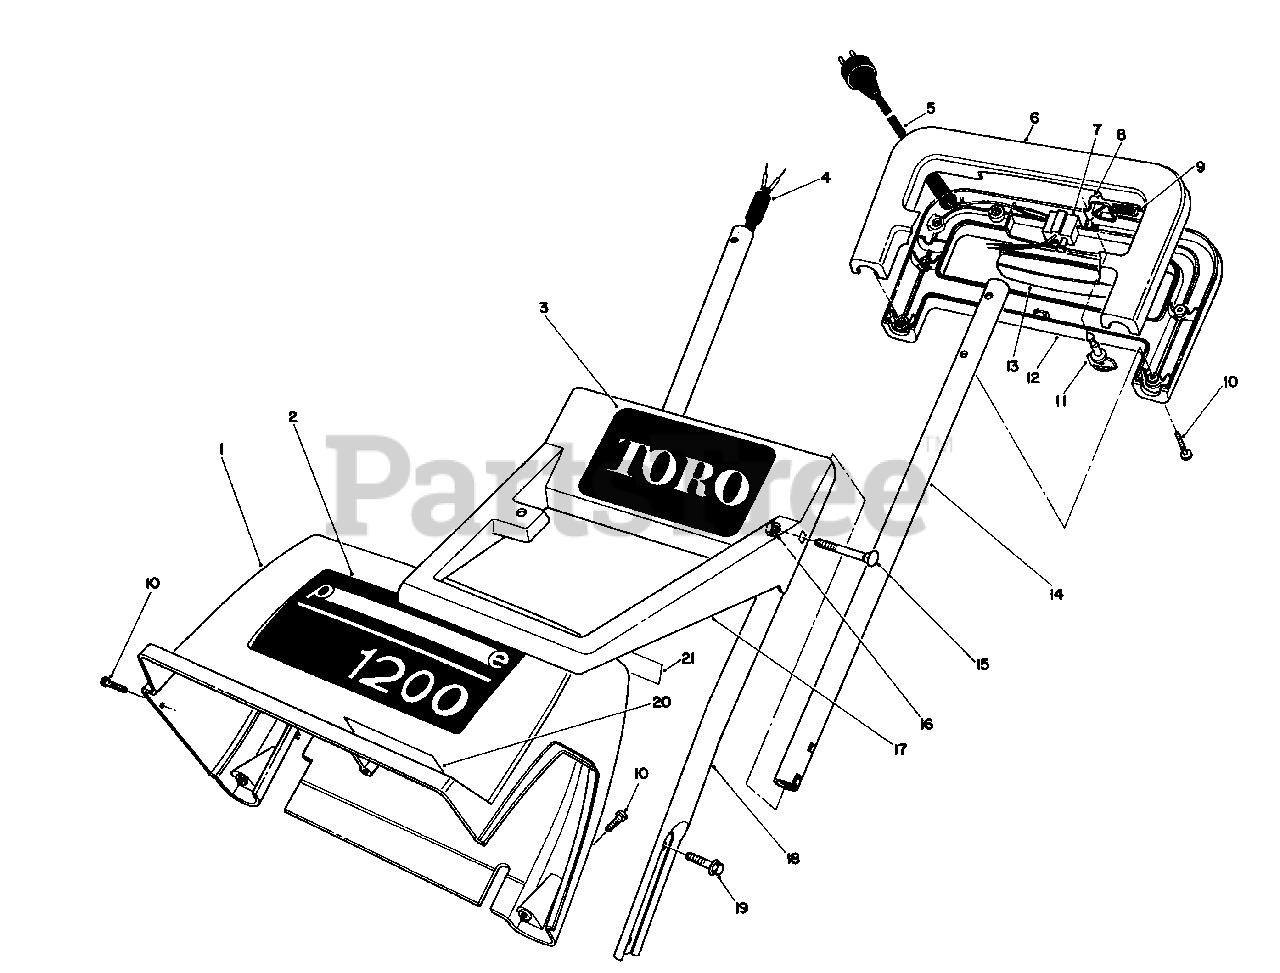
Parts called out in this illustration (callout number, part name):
1	Shroud (Incl. Ref. #2, 20, & 21)
2	Decal-1200
3	Decal-Toro
4	Wire Harness
5	Cord Supply
6	Handle-Upper Control
7	Switch-Starter
8	Switch-Lockout
9	Spring-Compression
10	Screw-Self Tap. Pan Hd.
12	Handle-Lower Control
13	Bar-Switch
14	Tube-Upper
15	Bolt-Carriage
16	Nut-Lock
17	Handle-Middle
18	Handle-Lower L.H.
19	Screw
20	Decal-Danger
21	Decal-U.L.
